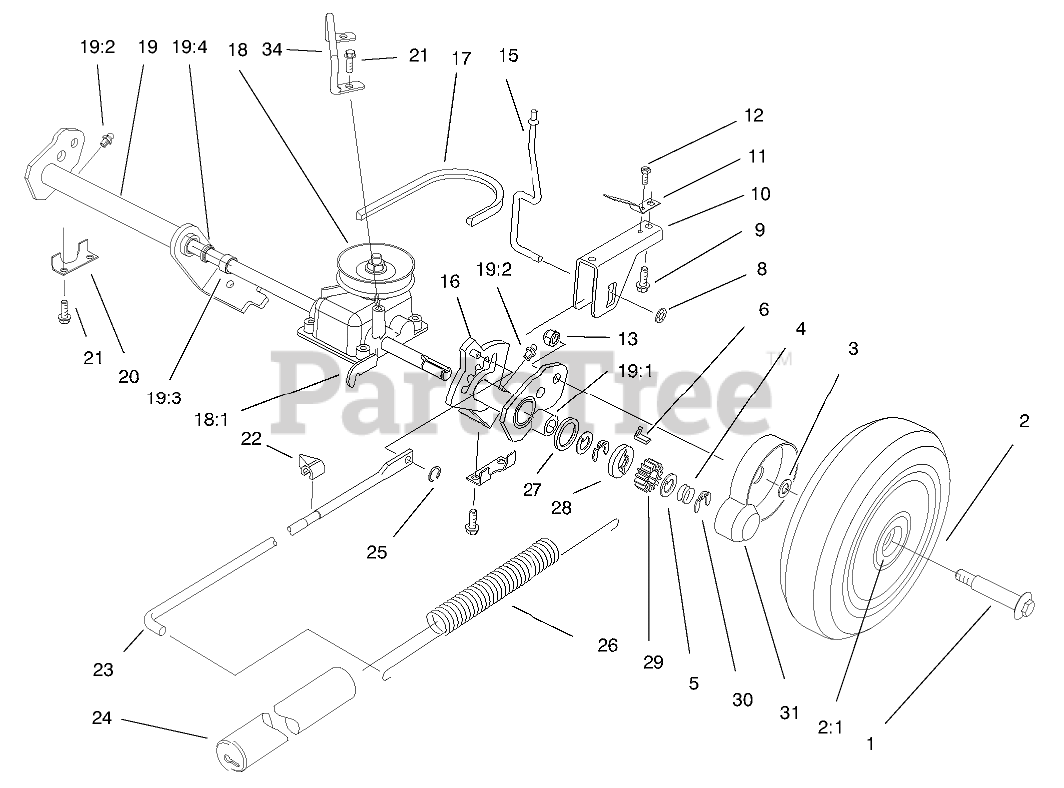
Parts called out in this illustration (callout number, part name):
1	BOLT-WHEEL
2	WHEEL AND TIRE ASM (WITH GEAR)
2:1	BUSHING
3	SPACER-COVER, WHEEL
4	SPRING-COMPRESSION
5	WASHER-THRUST, KEYED
6	KEY-ROCKING, LH
8	PUSHNUT
9	SCREW
10	SADDLE - HOC
11	SPRING - TRIGGER RET
12	SCREW 8 - 32 X 250
13	NUT-HEX
15	TRIGGER ROD
17	V-BELT
18	GEAR CASE ASSY
18:1	TRACTION BRACKET
19	ASM - RH PIVOT ARM
19:1	BEARING-ROLLER
19:2	FITTING-GREASE
19:3	BUSHING
19:4	SEAL-OIL
20	REAR SECURING PLATE
21	SCREW-HWH
22	INDICATOR-HEIGHT OF CUT
23	LINK ROD
24	COVER-SPRING
25	GRIP RING
26	SPRING-COUNTERBALANCE
27	RING-FRICTION
28	WASHER-CLUTCH
29	GEAR-PINION
30	RING-CLIP, LOCKING
31	COVER-WHEEL
34	Retainer Belt
